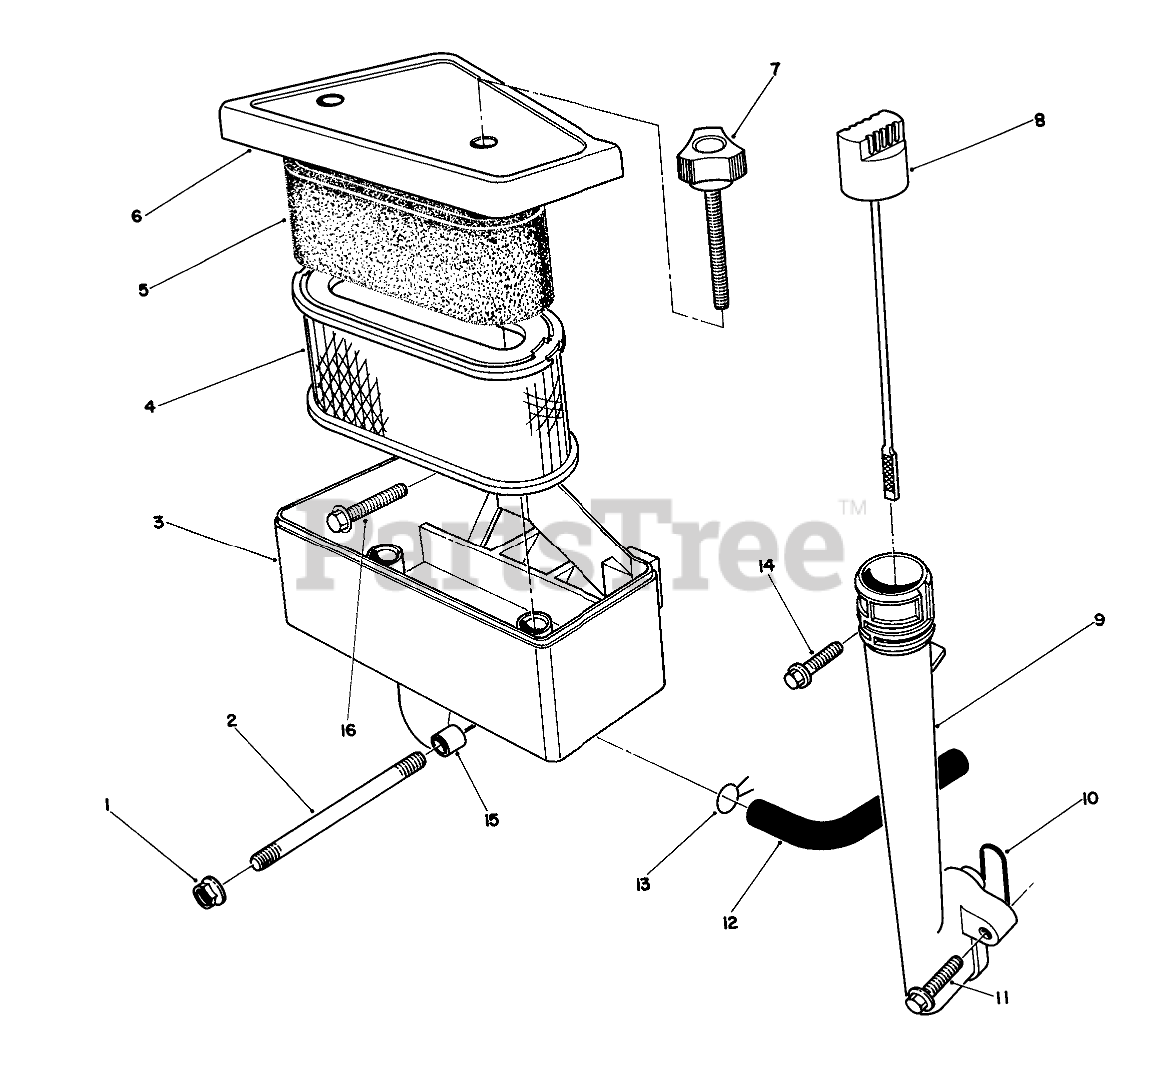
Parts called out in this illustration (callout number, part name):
3	AIR CLEANER BODY
4	Air Filter Assembly (Incl. Ref. #5)
5	Filter-Foam
6	AIR CLEANER COVER B
7	RETAINER - COVER
8	DIPSTICK
10	O-RING
13	CLAMP F/W ENGINE
15	SPACER
16	HEX FL HD M.6X1.0X25MM
